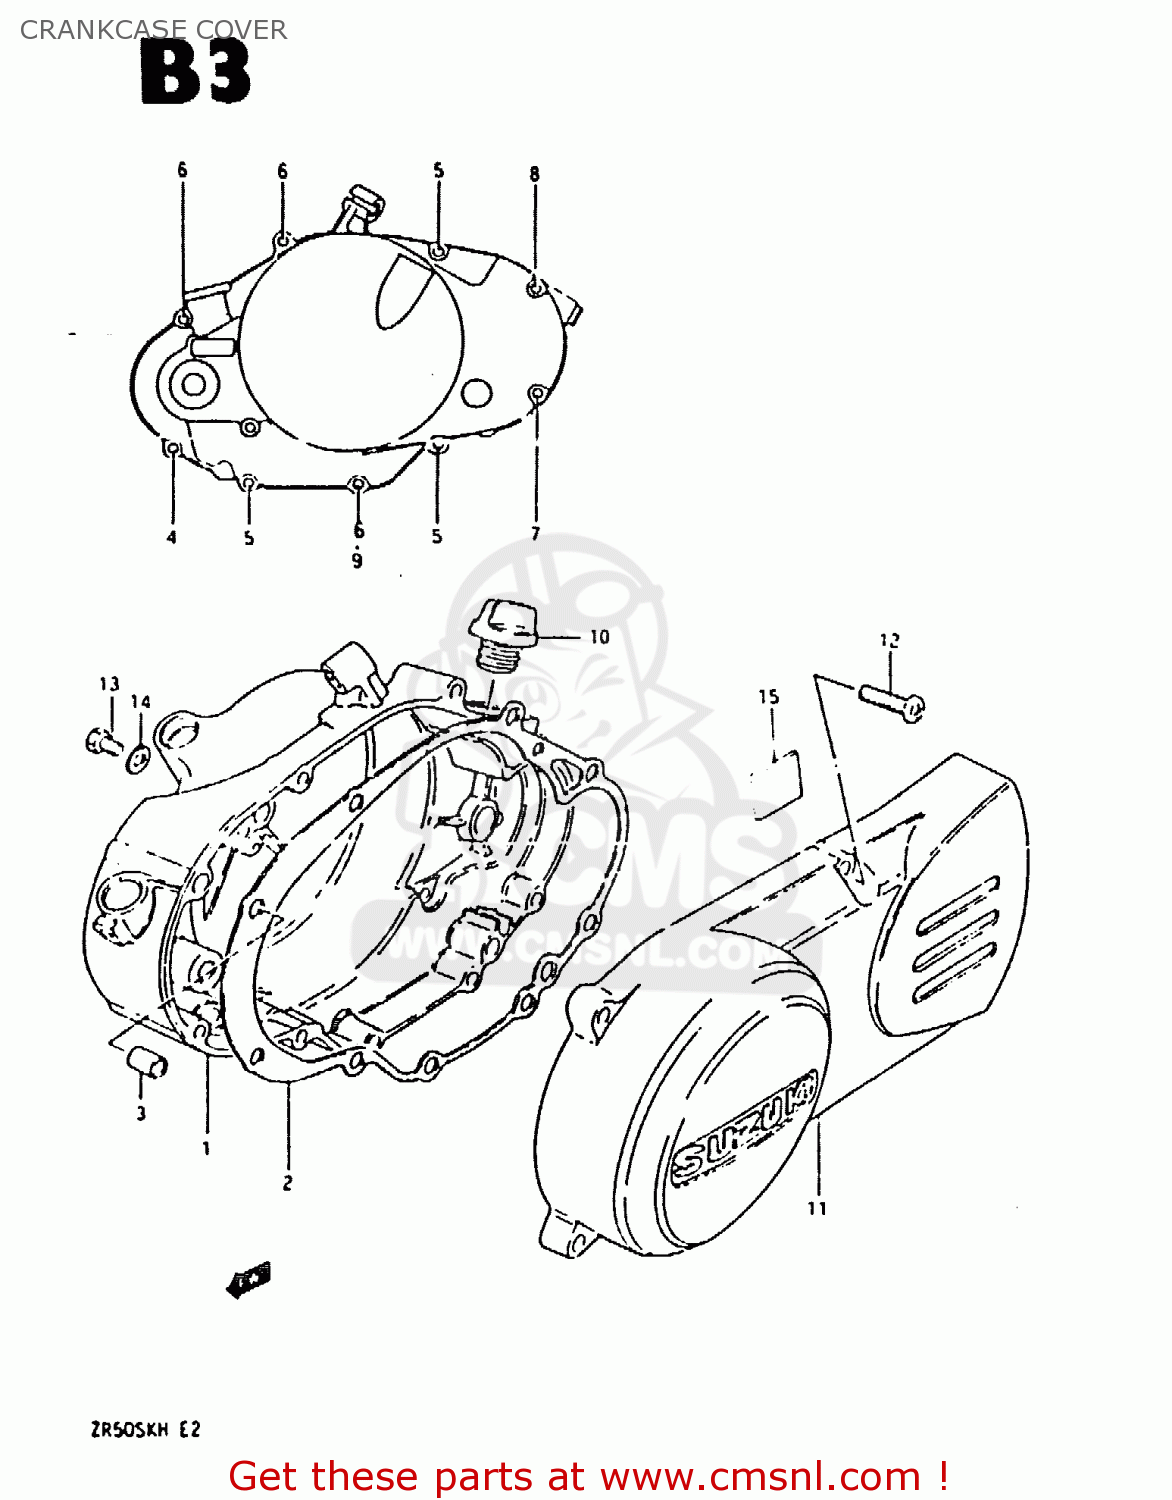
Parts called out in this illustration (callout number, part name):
1	COVER SET,CLUTCH
2	GASKET,CLUTCH COVER (MCA)
3	PIN
4	SCREW
5	SCREW 6X30
6	SCREW
7	SCREW
8	SCREW 6X60
9	GASKET(6.2X11X1).2 (NAS)
10	PLUG
11	COVER,MAGNETO
12	SCREW
13	SCREW(6X10)
14	GASKET(6.2X11X1) (NAS)
15	DAMPER,MAGNETO COVER
